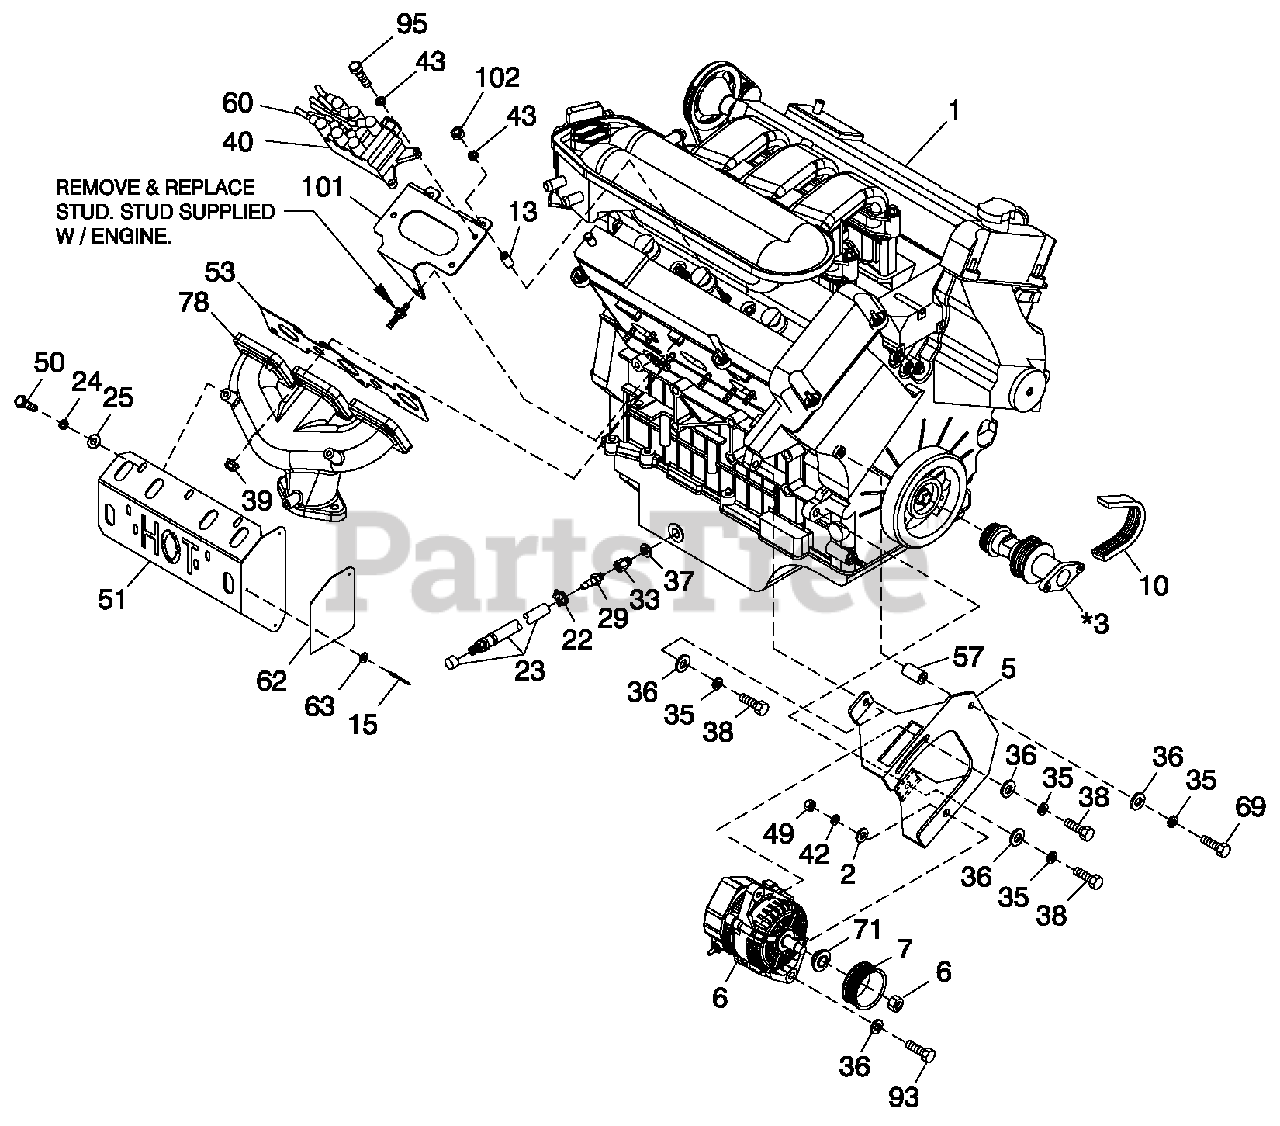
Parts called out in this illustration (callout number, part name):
1	HOSE 3/4 ID SAE-30R2 (28" LG)
2	FLANGE FUEL INLET
3	ASSY REGULATR 60KW LP
4	SCREW HHC M8-1.25 X 20 G8.8
5	WASHER FLAT 5/16 ZINC
6	WASHER LOCK M8-5/16
7	NUT HEX M8-1.25 G8 CLEAR ZINC
8	HOSE 3/8 ID SINGLE BRAID (17" LG)
9	NIPPLE CLOSE 3/4 X 1.375
10	ELBOW 90D 3/4 NPT
11	NIPPLE PIPE 3/4 NPT X 7
12	HARNESS FUEL JUMPER SINGLE REG
13	CLAMP HOSE #8 .53-1.00
14	HOSE 3/4 ID SAE-30R2 (22" LG)
15	CLAMP HOSE #44 2.31-3.25
16	DECAL INLET PRESSURE
17	DECAL FUEL INLET LPG
18	INTAKE ADAPTER BOSCH
19	GASKET BOSCH 32
20	ACTUATOR BOSCH 40 GOVERNOR
21	REDUCER RUBBER 3.0"-2.00"
22	MIXER 40/60MM ACTUATOR ASSY
23	O-RING 2-3/4 X 3/32 X 2-15/16
24	VENTURI THROTTLE 32MM
25	SCREW SHC M6-1.0 X 25 G12.9 ZP
26	WASHER LOCK M6-1/4
27	SCREW HHC M6-1.0 X 50 G8.8
28	CLAMP HOSE #36 1.88-2.75
29	CLAMP HOSE #10 .56-1.06
30	HOSE COOL 5/8" ID 250#WP (11" LG)
31	BARBED Y 5/8-HOSE
32	ADAPTER INSERT HOSE BARB 5/8"
33	CAP VINYL .5" ID X 1.0" DP BLK
34	CAP VINYL 3/8" ID X 1" DP BLK
35	CLAMP HOSE .38-.87
36	COVER FUEL INLET NG
37	BARBED EL 90 1/4 NPT X 3/8
38	HOSE COOL 5/8" ID 250#WP (14.5" LG)
39	HOSE COOL 5/8" ID 250#WP (18.5" LG)
